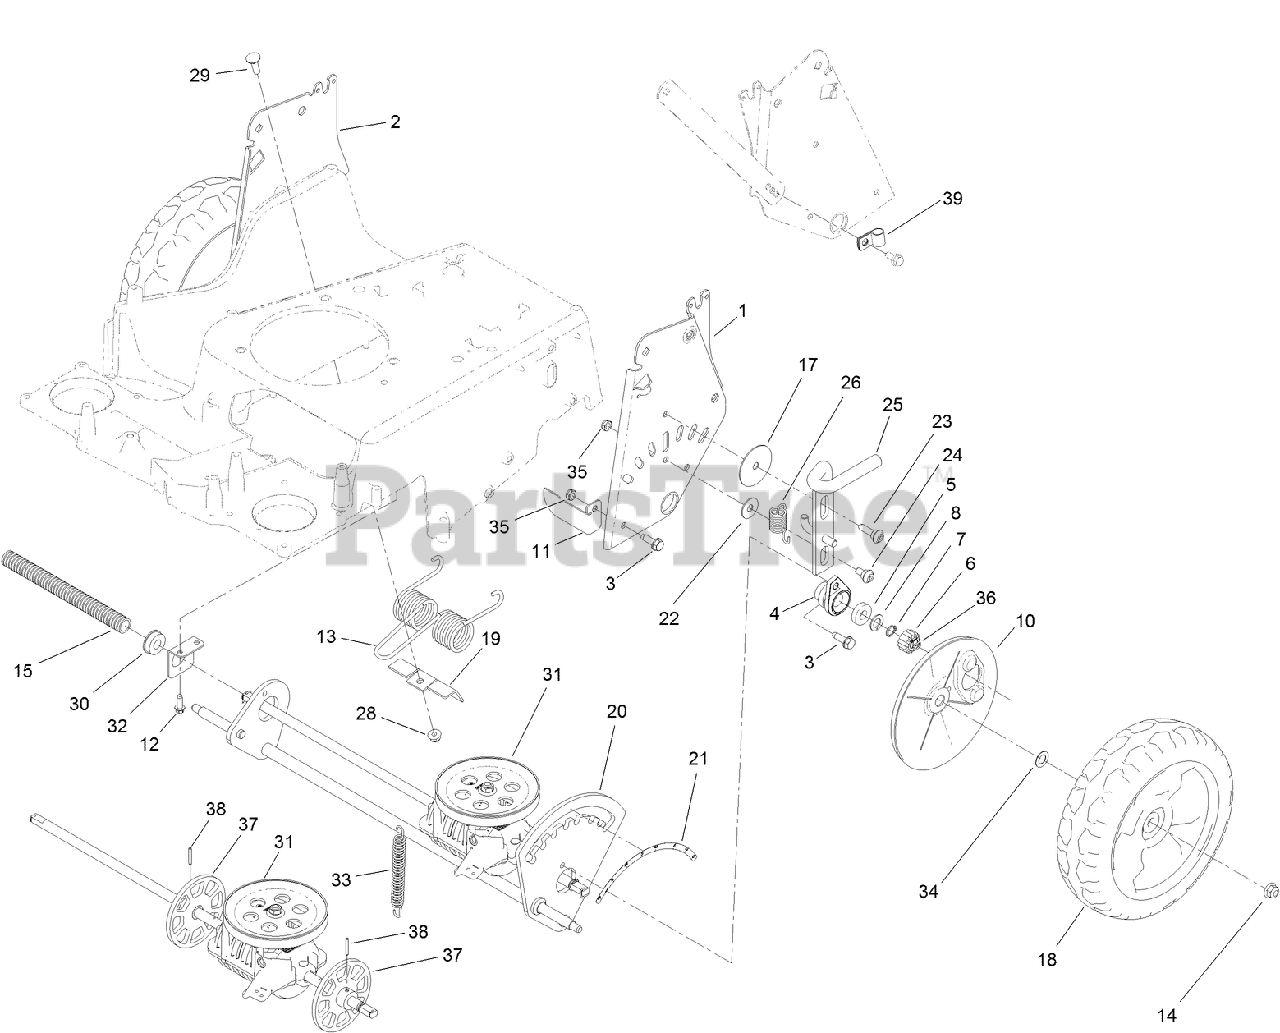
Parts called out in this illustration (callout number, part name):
1	LH HOC PLATE ASM
2	RH HOC PLATE ASM
3	SCREW-HWHTF
4	RETAINER-BEARING
5	BEARING-BALL
6	GEAR-PINION, 15T
7	RING-RETAINING
8	WASHER-THRUST
10	COVER-GEAR
11	BRACKET-STOP
12	SCREW-HWHTF
13	SPRING-TORSION
14	NUT-HF, NI
15	CONDUIT-CONVOLUTED
17	WASHER-PLAIN
18	10.5 INCH WHEEL ASM
19	BRACKET
20	AXLE-REAR
21	DECAL-HOC, REAR
22	WASHER
23	SCREW-SHOULDER, BHTF
24	BOLT-SHOULDER
25	LOCK-HEIGHT, ADJUST
26	SPRING-EXTENSION
28	NUT-HF, NI
29	BOLT-CARR
30	BEARING-BALL
31	TRANSMISSION
32	MOUNT-BEARING
33	SPRING-EXTENSION
34	WASHER-PLAIN
35	NUT-LOCK, NI
36	PIN-SNAP
37	ROTOR ASM
38	PIN-ROLL
39	R-CLAMP
